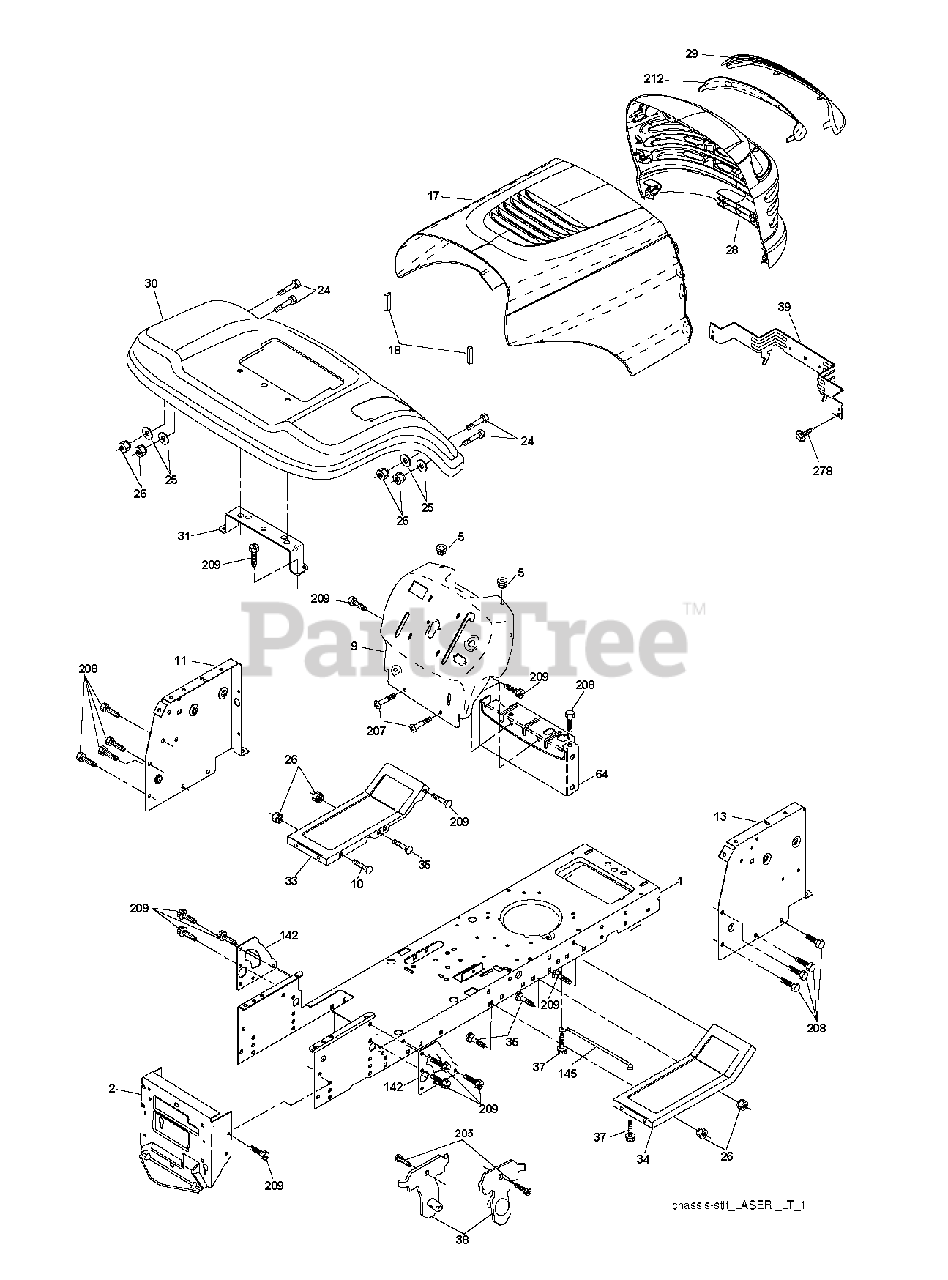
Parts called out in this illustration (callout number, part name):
1	CHASSIS STAMPING
2	DRAWBAR, 12GA
5	BUMPER.RUBBER.HOOD
9	DASH
10	BOLT D
11	PANEL.DASH.LH.LTX
18	BUMPER.HOOD.LARGE.1.75"
25	WASHER
26	NUT
28	LENS LASER.LT.CLEARBAR
29	LENS.LASER LT.CLEAR.BAR
31	BRACKET FENDER
38	BRACKET.ASM.PIVOT.MOWER.REAR
39	BRACKET PIVOT
64	DASH LOWER
142	PLATE REINFORCEMENT
145	ROD.PIVOT.HOOD
207	SCREW, 5/16-18 X 1/2
208	SCREW 3/8-16X1/2
209	SCREW, 3/8-16X3/4
278	SCREW.#10 X 0.750.BOS THREAD
